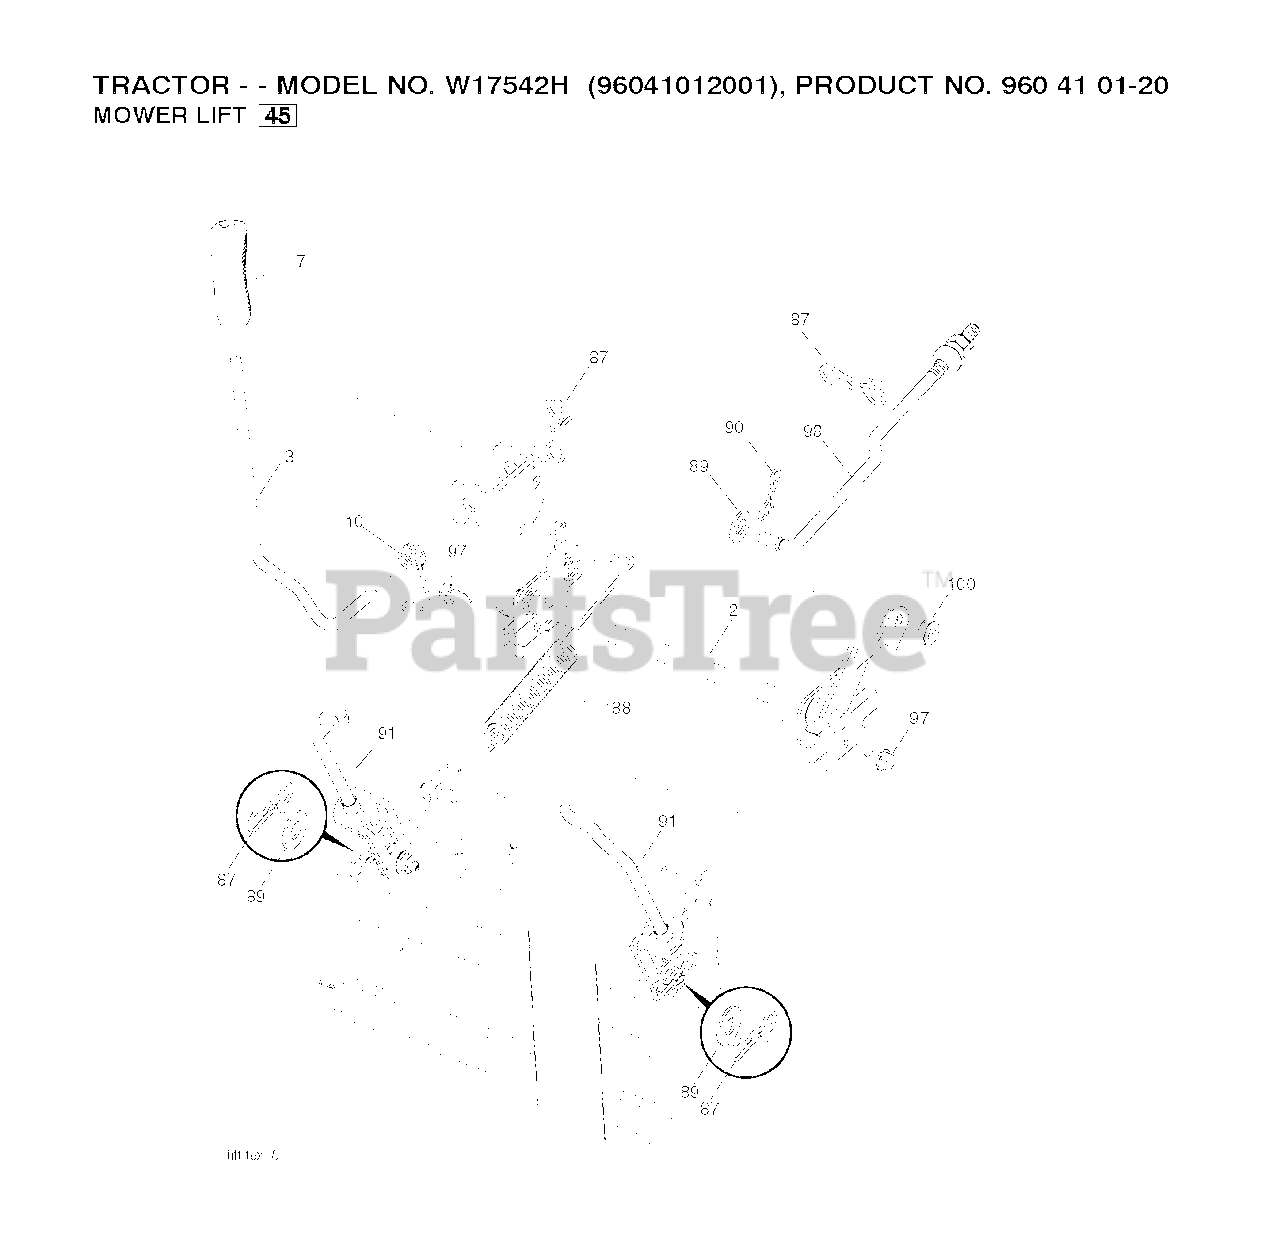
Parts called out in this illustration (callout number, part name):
2	SHAFT.ASM.LIFT.CROSS.H
3	LEVER.LIFT.HANDLE.LT
7	GRIP.LEVER.
10	SPRING.TORSION.LIFT.HANDLE
87	PIN.COTTER.7/16.BOW TI.
88	SPRING.LIFT.ASSIST
90	PIN.COTTER.5/16.BOW TI
91	LINK.ASM.LIFT.REAR
97	SCREW, 3/8-16X3/4
98	LINK.ASM.SUSP.FRONT.MW
100	LOCKNUT
